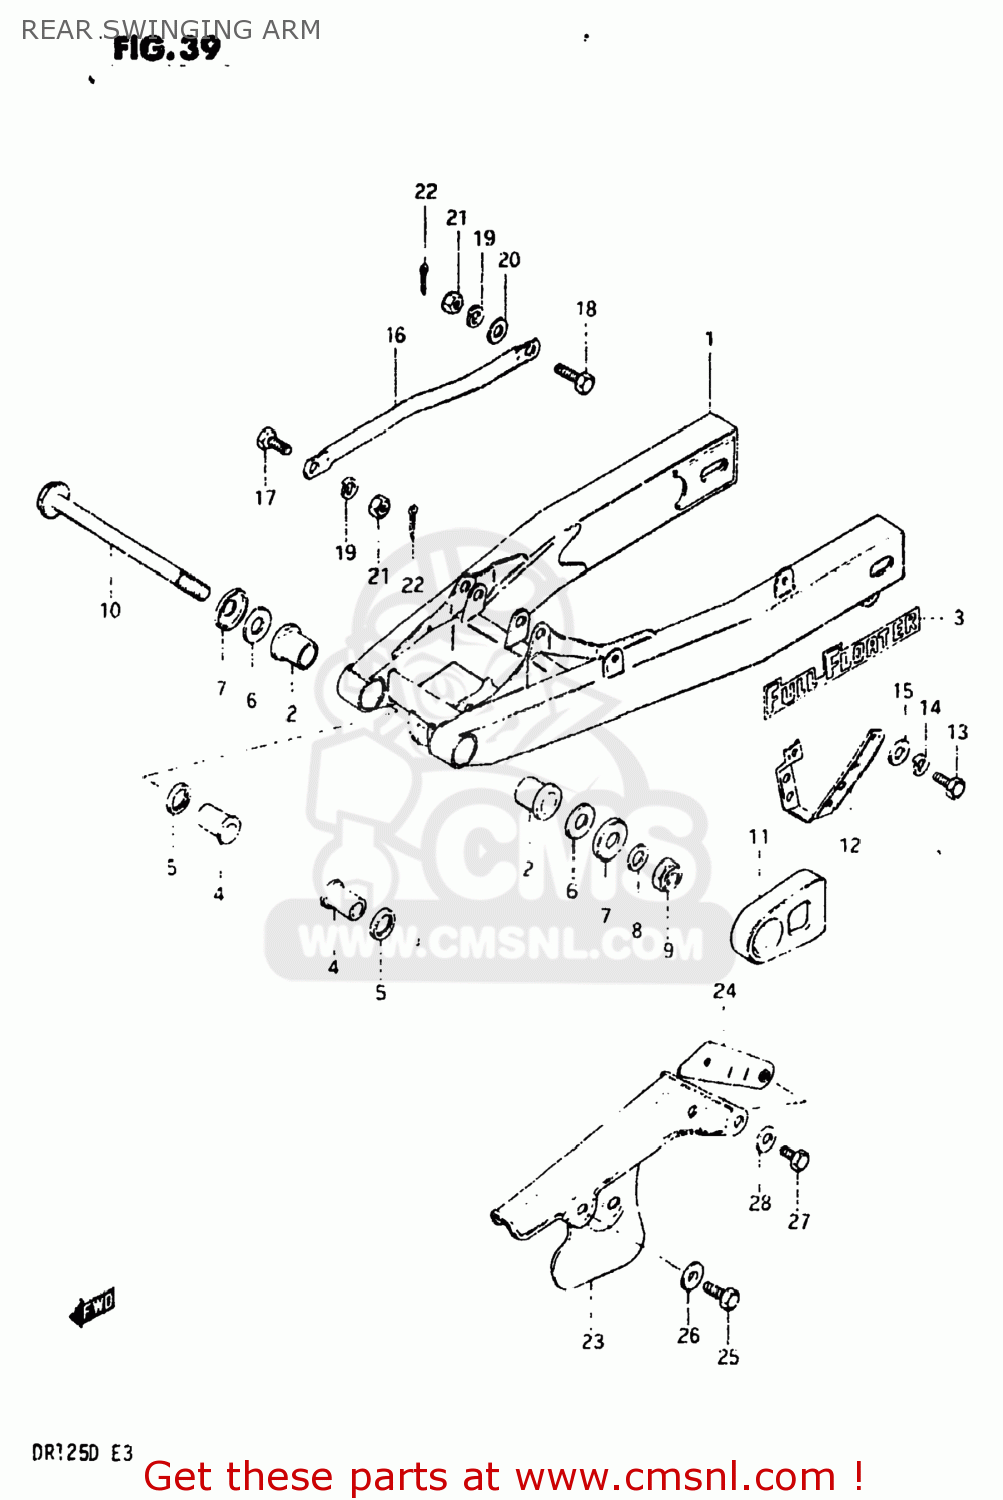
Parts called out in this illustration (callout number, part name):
1	SWING ARM ASSEMBLY,REAR
2	BUSHING,REAR SWING ARM PIVOT
3	EMBLEM,SWING ARM
4	SPACER,RR SWGARM PIVOT
5	SEAL,OIL(20X27X5)
6	WASHER
7	CVR,RR SWGARM DUST SEAL(OD:40)
8	WASHER
9	NUT 14MM
10	SHAFT,REAR SWING ARM
11	BUFFER,CHAIN TOUCH DEFENSE
12	GUIDE,CHAIN
13	BOLT 8X12
14	LOCK WASHER
15	WASHER
16	TORQUE LINK,REAR
17	BOLT(8X22)
18	BOLT(8X26.5)
19	LOCK WASHER
20	WASHER
21	NUT
22	PIN 20X20
23	CASE,CHAIN
24	REINFORCEMENT,CHAIN CASE
25	BOLT(6X8)
26	WASHER
27	BOLT, UPPER
28	WASHER
